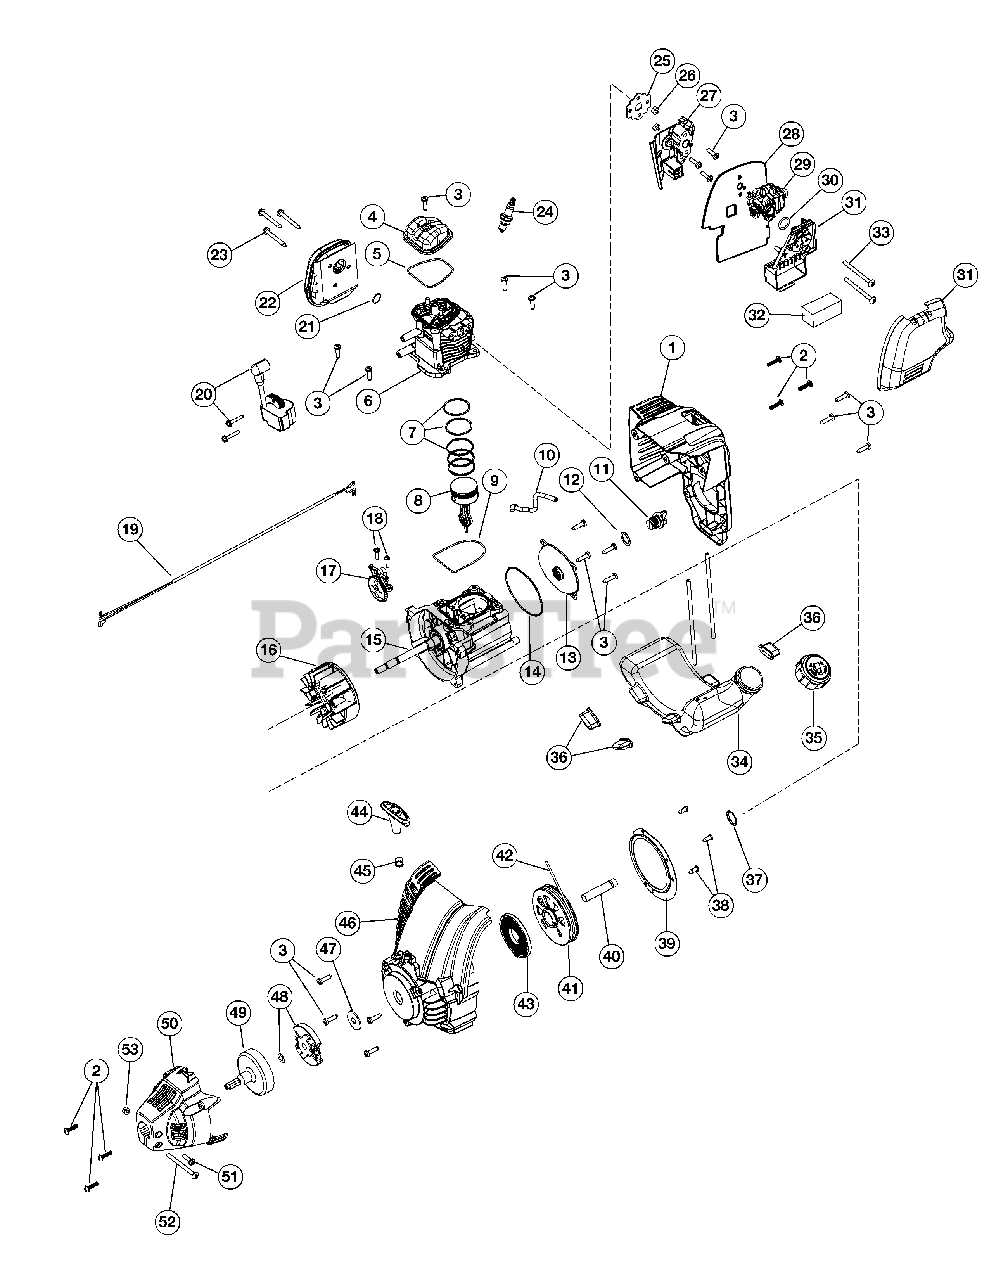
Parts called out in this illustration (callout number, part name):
1	Engine Cover Assembly (Incl. Ref No. 2 & 3)
2	Cover Screw
3	Screw
4	Rocker Cover
5	Rocker Cover O-Ring
6	Cylinder Assembly (Incl. Ref No. 3, 5 & 9)
7	Piston Ring Assembly
8	Piston Assembly (Incl. Ref No. 7)
9	Cylinder O-Ring
10	Breather Hose
11	Oil Plug (Incl. Ref No. 12)
12	Oil Plug O-Ring
13	Crankcase Cover
14	Crankcase Cover O-ring
15	Crankcase Assembly (Incl. Ref No. 9, 10 & 14)
16	Flywheel Assembly
17	Cam Bracket Assembly (Incl. Ref No. 18)
18	Cam Bracket Screw
19	Lead Wires
20	Module Assembly
21	Muffler Gasket
22	Muffler Assembly (Incl. Ref No. 21 & 23)
23	Muffler Screw
24	Spark Plug
25	Insulator Gasket
28	Carburetor Gasket
29	Carburetor w/Primer
31	Air Cleaner Cover Assembly (Incl. Ref No. 32)
32	Air Filter
34	Fuel Tank Assembly w/Fuel Lines (Incl. Ref No. 35)
36	Fuel Tank Pads
38	Pressure Plate Screw
39	Pressure Plate (Incl. Ref No. 38)
41	Starter Assembly (Incl. Ref No. 42)
43	Recoil Spring
44	Handle
46	Starter Housing Assembly (Incl. Ref No. 3 & 37-45)
48	Clutch & Clutch Washer
49	Clutch Drum
50	Clutch Cover (Incl. Ref No. 2)
51	Anti-Rotation Screw
52	Clamp Screw
53	Nut
